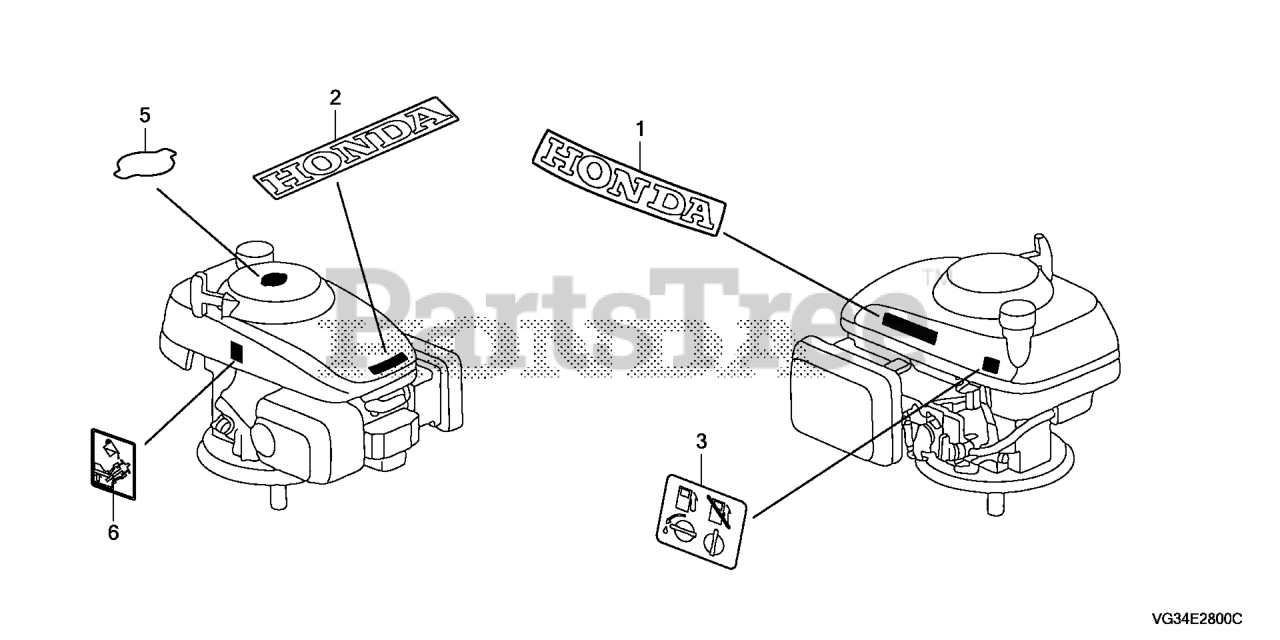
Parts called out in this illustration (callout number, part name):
2	MARK, HONDA (TYPE1) (RED)
2	MARK, HONDA *R280* (POWER RED)
3	MARK, FUEL PETCOCK CAUTION
